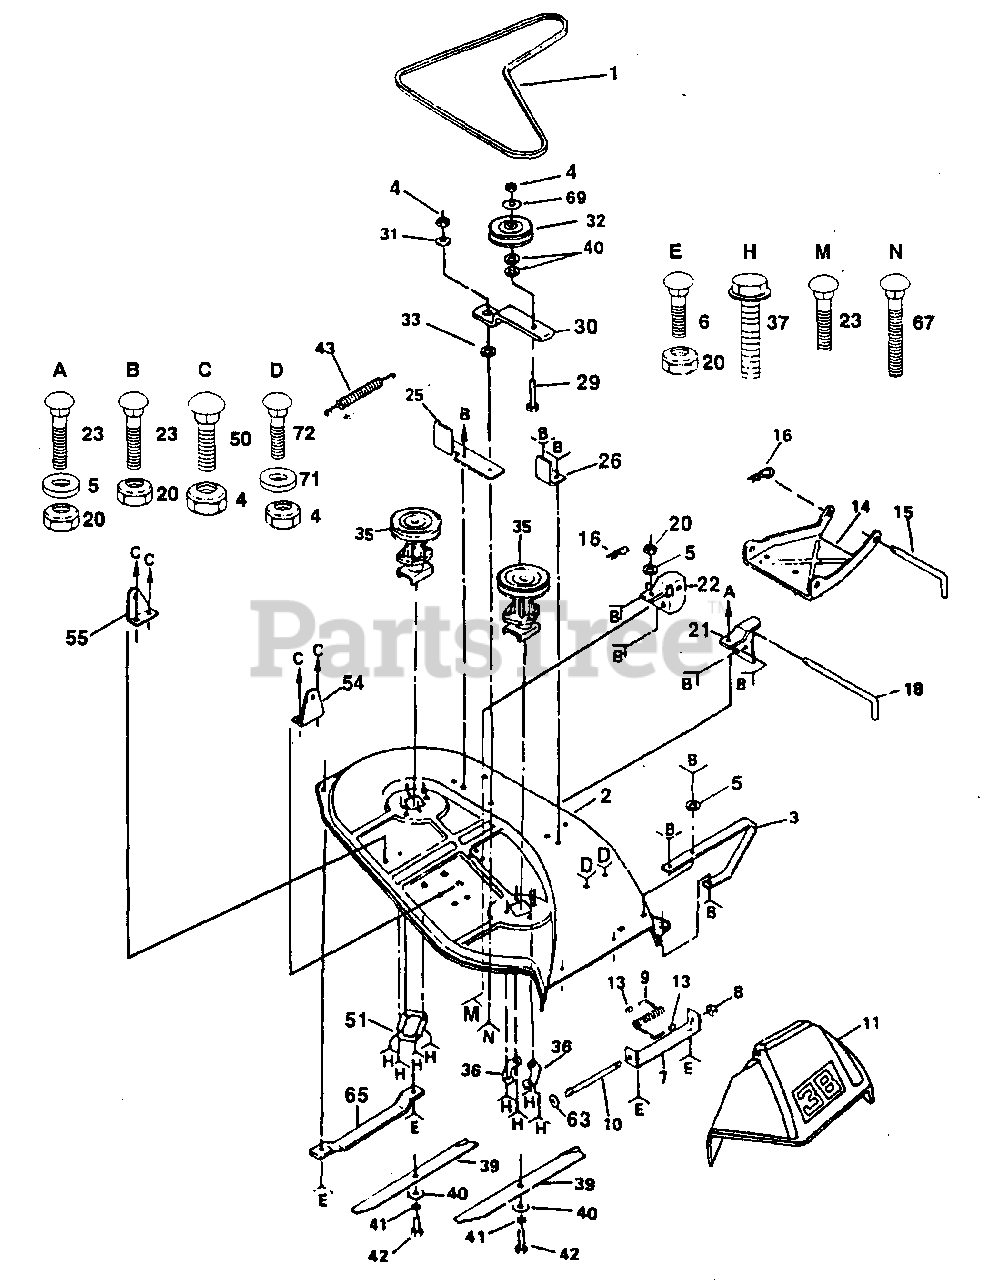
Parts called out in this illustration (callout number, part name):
1	V-Belt (AYP part number)
2	Housing (AYP part number)
3	Runner, R. H. (AYP part number)
4	Locknut 3/8-16
5	Washer 11/32 x 3/4 x 16 Ga. (AYP part number)
6	Bolt, Carriage 5/16-18 x 5/8 (AYP part number)
7	Bracket, Deflector (AYP part number)
8	Pushnut (AYP part number)
9	Spring, Deflector (AYP part number)
10	Rod, Hinge (AYP part number)
11	Shield, Deflector (AYP part number)
13	Cap (AYP part number)
14	Link, Parallel (AYP part number)
15	Pin, Hinge, Front (AYP part number)
16	Sprint, Retainer (AYP part number)
18	Pin, Hinge, Rear (AYP part number)
20	Locknut 5/16-18
21	Bracket, Lift, R. H. (AYP part number)
22	Bracket, Lift, L. H. (AYP part number)
23	Bolt, Carriage 5/16-18 x 3/4
25	Support, Arm (AYP part number)
26	Stop, Deck, Front (AYP part number)
29	Bolt 3/8-16 x 2 (AYP part number)
30	Arm, Idler (AYP part number)
31	Spacer (AYP part number)
32	Pulley, Idler (AYP part number)
33	Washer, Wear 1/16 (AYP part number)
35	Mandrel Assembly (AYP part number)
36	Plate, Support, Mandrel (AYP part number)
37	Screw, Hex Washer Head 3/8-16 x 1-1/4 (AYP part number)
39	Blade
40	Washer 13/32 x 1-3/4 x 10 Ga. (AYP part number)
41	Washer, Lock 3/8 (AYP part number)
42	Bolt, Hex 3/8-24 x 1-1/2 Gr. 5 (AYP part number)
43	Spring, Extension (AYP part number)
50	Bolt, Carriage 3/8-16 x 3/4 (AYP part number)
51	Plate, Support (AYP part number)
54	Bracket, Suspension, Rear, R. H. (AYP part number)
55	Bracket, Suspension, Rear, L. H. (AYP part number)
63	Washer 11/32 x 5/8 x 16 Ga. (AYP part number)
65	Runner, L. H. (AYP part number)
67	Bolt, Carriage 3/8-16 x 1-1/4 (AYP part number)
69	Washer 13/32 x 13/16 x 16 Ga. (AYP part number)
71	Washer 7/16 x 1 x 10 Ga. (AYP part number)
72	Bolt, Carriage 3/8-16 x 3/4 (AYP part number)
